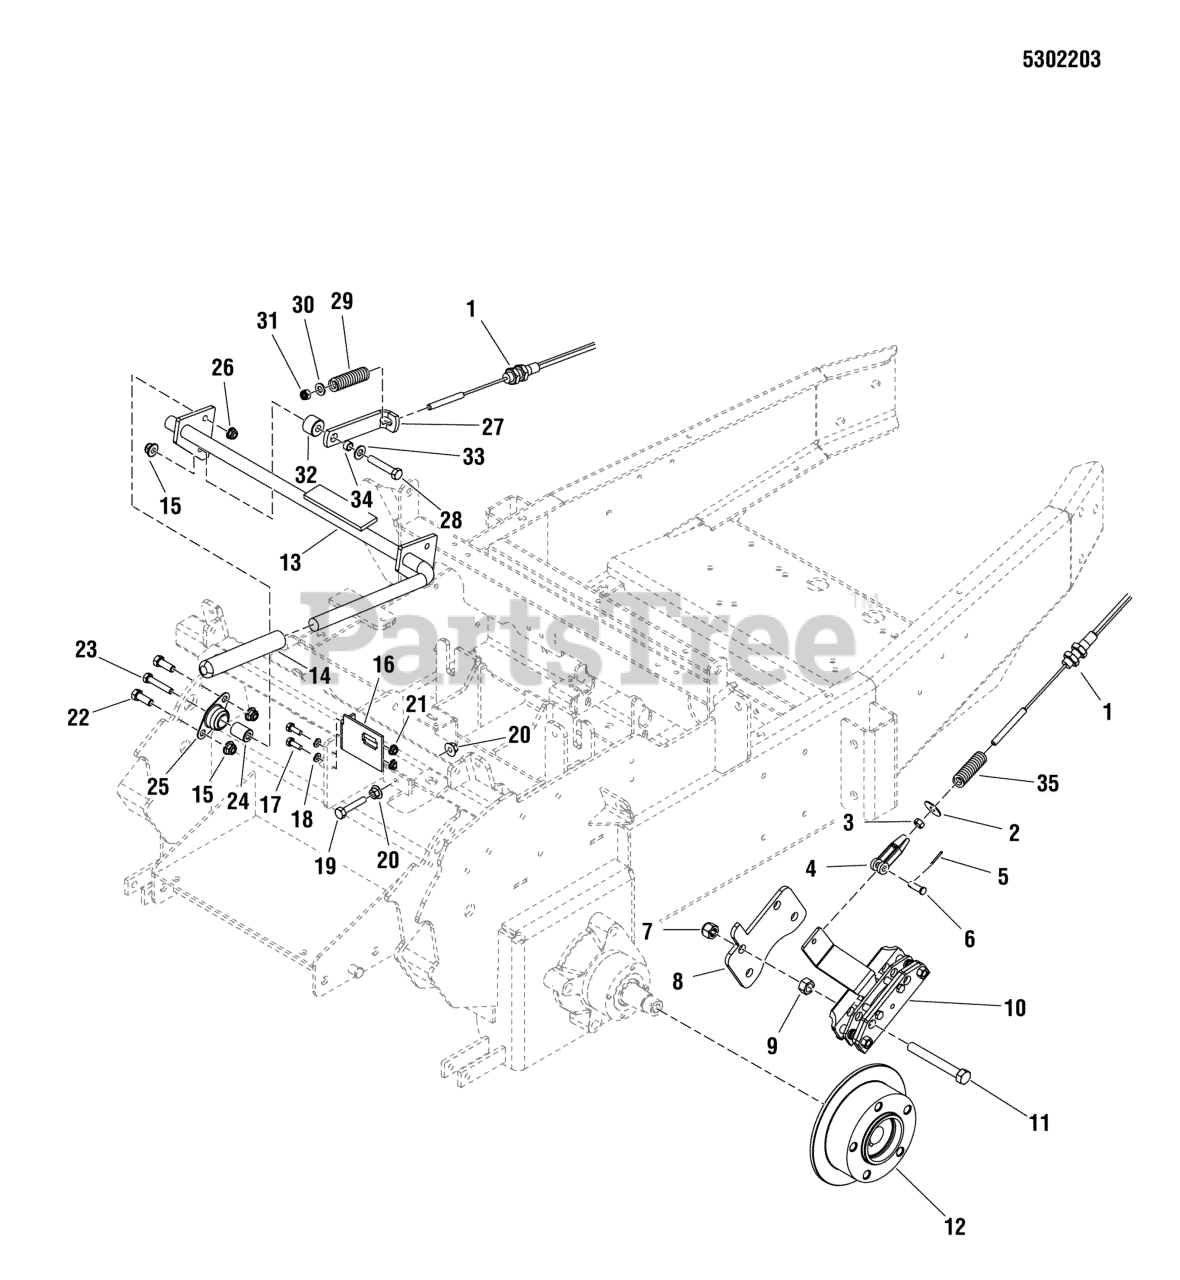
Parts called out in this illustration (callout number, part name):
1	CABLE, PARKING BRAKE IS2000
2	WASHER, 5/16 FENDER
3	NUT, 5/16-24 HEX
4	CLEVIS, 5/16-24, PLASTIC
5	PIN, 3/32 X 0.750, COT, ZINC/CLEAR
6	PIN-CLEVIS, 5/16 X 1 YZ
7	NUT, 1/2-13 HEX NYLON LOCK
8	MOUNT, BRAKE CALIPER - RED
9	NUT, 1/2-13 HEX
10	COMPACT CALIPER, AUSCO (86978)
11	BOLT, 1/2-13 X 4" GD5 CZ
12	WHEEL HUB, COMPACT CALIPER (86720)
13	WELD, BRAKE SHAFT - RED
14	GRIP, FOAM, 3/4 ID X 6 X .187
15	NUT, 3/8-16 HEX NYLOCK FLANGE
16	BRACKET, SWITCH MOUNT - RED
17	BOLT, 1/4-20 X 3/4 GD5 YZ
18	WASHER, 1/4 SAE
19	BOLT- 5/16-18 X 1-3/4 GD5 TFL
20	NUT, 5/16-18 HEX SERRATED FLANGE (LARGE)
21	NUT, 1/4-20 HEX SERR. FLANGE
22	BOLT, 3/8-16 X 1" GD5 CZ
23	BOLT, 5/16-18 X 1-3/4 GD5 YZ
24	SPACER, .32 X .75 X 1.06
25	BEARING, BRONZE FLANGE, 3/4
26	NUT, 5/16-18 HEX NYLOCK FLANGE
27	LINK, BRAKE LOCK - BLK
28	BOLT, 3/8-16 X 2, GD5, CZ
29	SPRING-COMP, .75 X .162 X 2.5
30	WASHER, 5/16" SAE
31	NUT, 5/16-24 HEX NYLON LOCK
32	SPACER, .39 X 1.00 X .75
33	WASHER, 3/8 SAE
34	SPACER, .38 X .50 X .27
35	SPRING, COMPRESSION, 5-1/2
